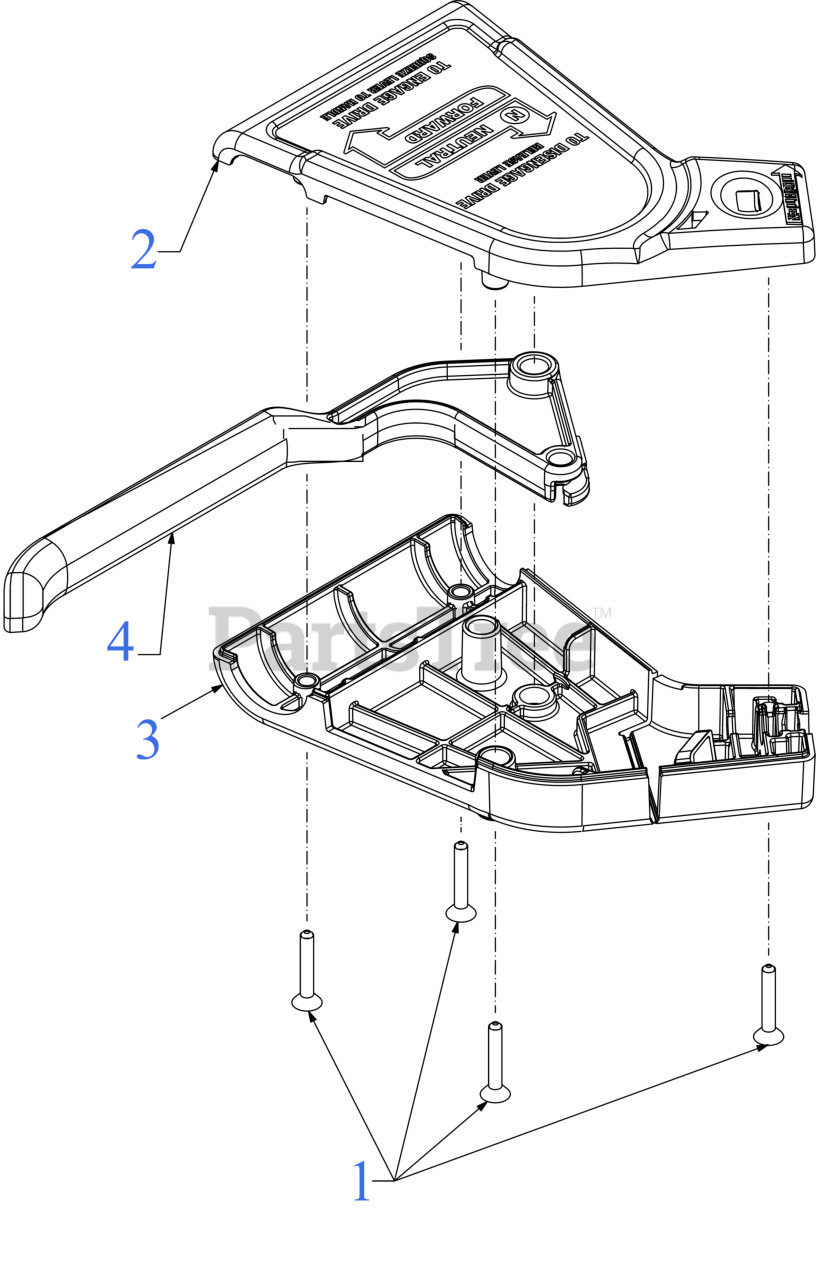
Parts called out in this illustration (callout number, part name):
1	SCREW #10-16 x 1.00
2	KIT-DRIVE CONTROL
3	SQUEEZEBOX CONTROL COVER
4	ENGAGEMENT LEVER (YELLOW)
